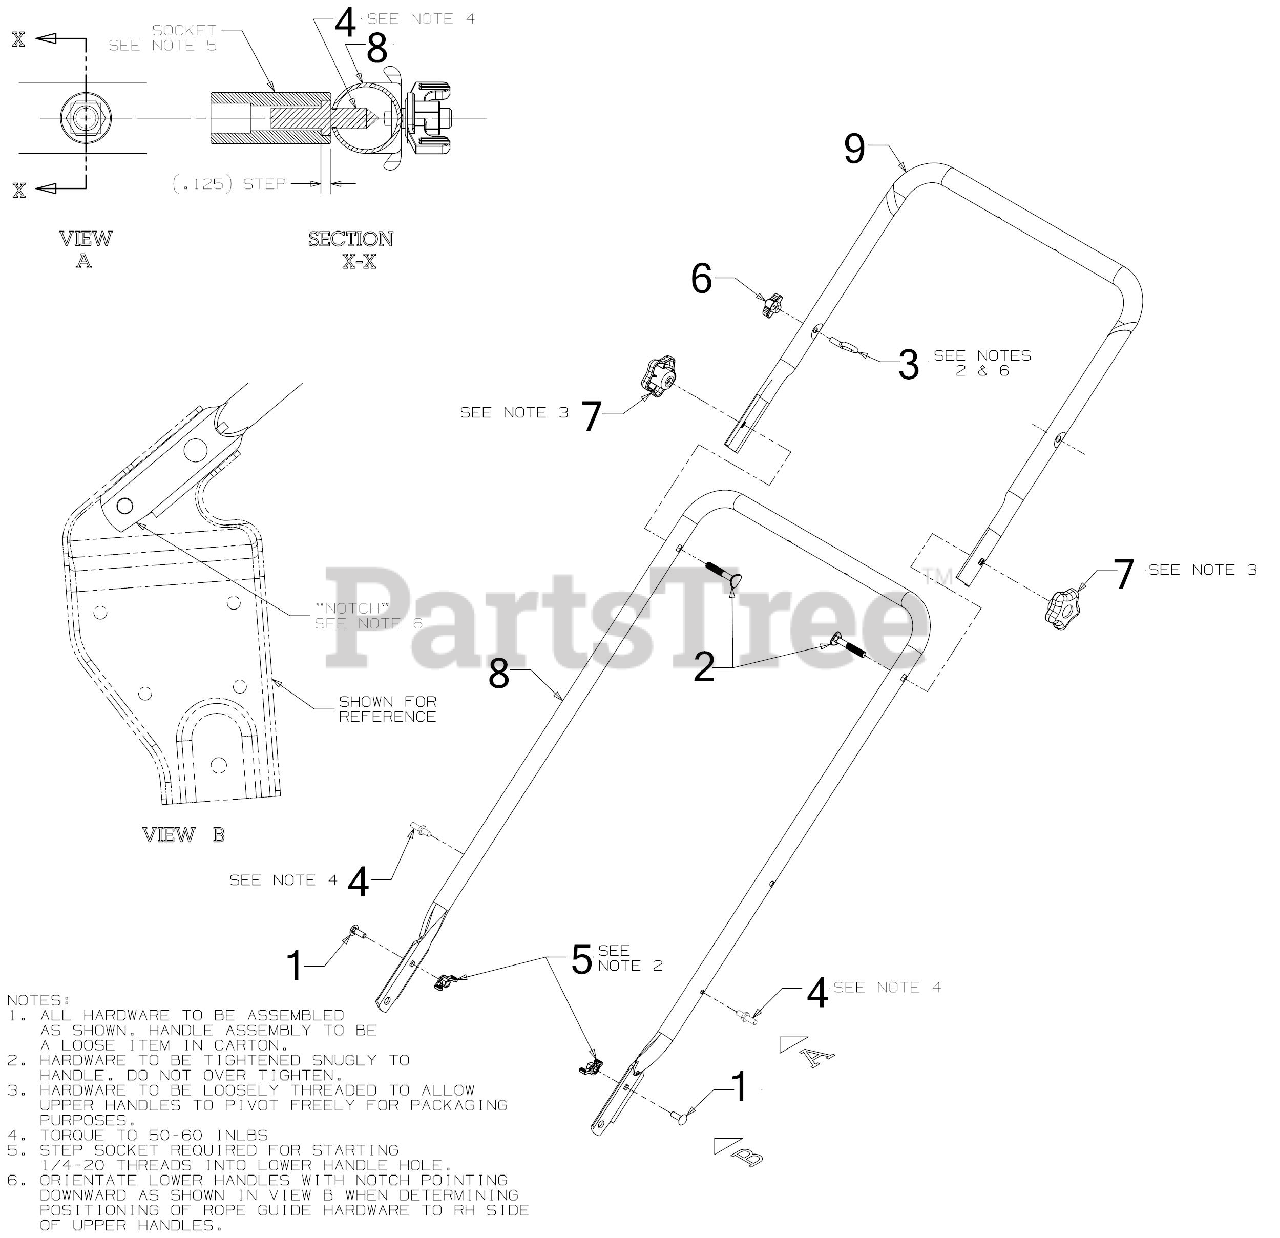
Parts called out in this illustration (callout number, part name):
1	SCREW 1/4-20 x .75 GR5
2	SCREW .312-18X2.0
3	EYEBOLT 1/4-20
4	BELT KEEPER PIN 1/4-20
6	HANDLE KNOB
7	STAR KNOB 5/16-18
